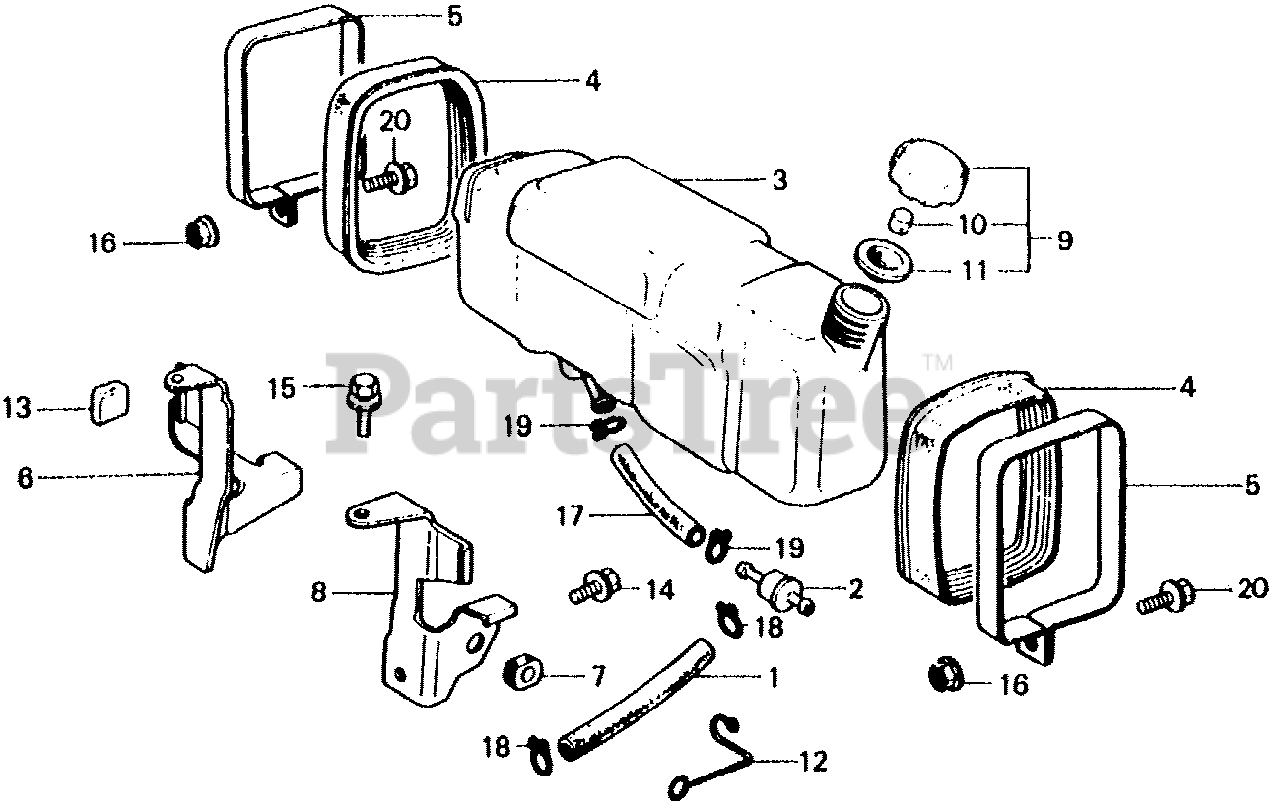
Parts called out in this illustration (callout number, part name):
1	BULK HOSE, FUEL (4.5X3000) (4.5X120)
1	BULK HOSE, FUEL (4.5X3000) (Honda Code 5137104). (4.5X115)
2	FILTER, FUEL
3	TANK, FUEL *NH1* (BLACK)
4	RUBBER, TANK SEAT
5	BAND, FUEL TANK
6	STAY A, TANK
7	GROMMET, FUEL TUBE
8	STAY B, TANK
9	CAP, FUEL TANK
10	SPONGE, FUEL CAP BREATHER
11	GASKET, FUEL CAP
12	CLAMP, IGNITION WIRE
13	RUBBER, CUSHION
14	BOLT, FLANGE (6X12) (CT200)
15	BOLT-WASHER (6X10)
16	NUT, FLANGE (6MM)
17	BULK HOSE, FUEL (5.5X8000) (5.5X110)
17	TUBE, FUEL
18	CLIP, TUBE (B8)
19	CLIP, TUBE (B10)
20	BOLT, FLANGE (6X12)
